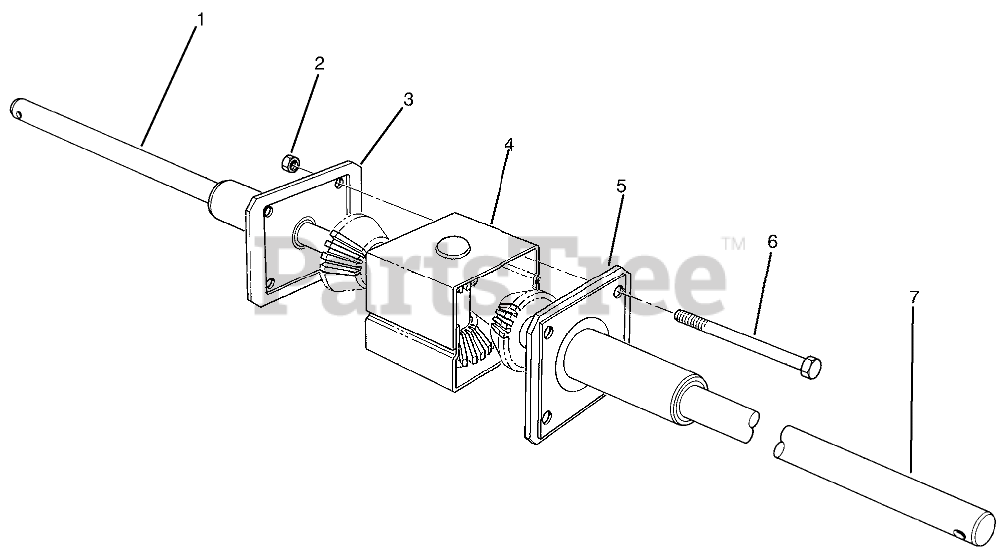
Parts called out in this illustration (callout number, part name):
2	NUT-LOCK, CONE
3	END CAP/BRG ASM
4	GEAR CASE ASM
5	END CAP &BEARING ASY
6	SCREW-HH
